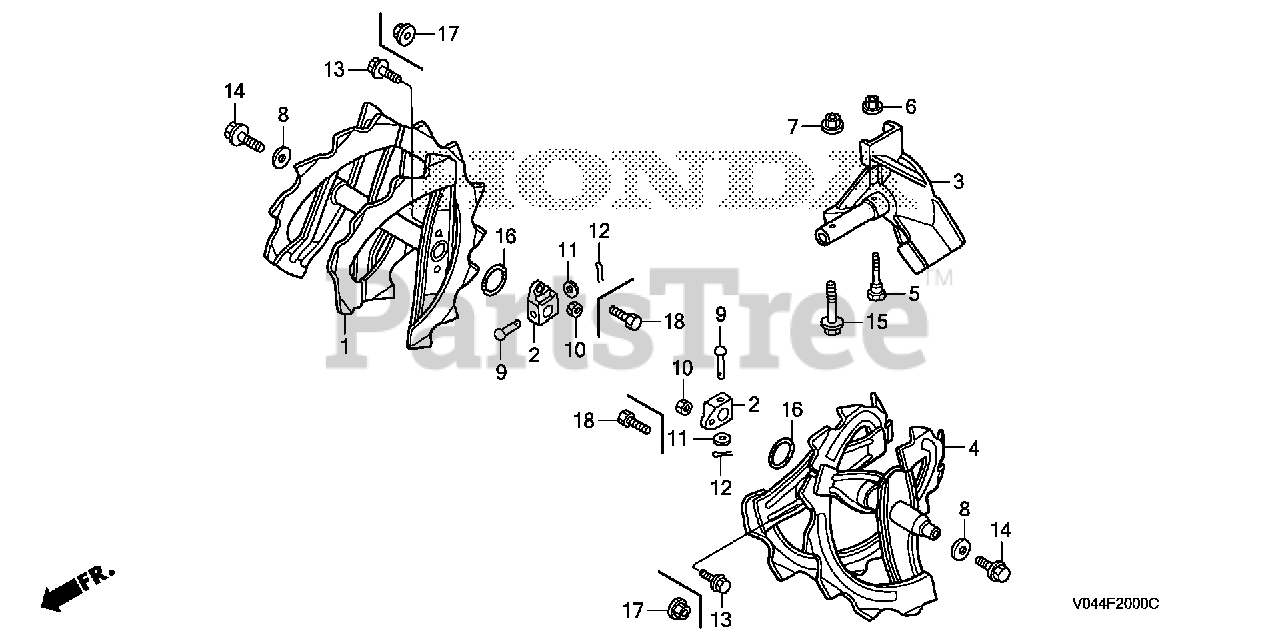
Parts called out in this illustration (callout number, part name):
2	BOSS, LOCK BOLT
5	BOLT, LOCK
6	NUT, SELF-LOCK (6MM)
7	NUT, FLANGE (8MM)
8	WASHER (8MM)
9	PIN (7X40)
11	WASHER, PLAIN (7MM)
12	PIN, SPLIT (3.0X25)
12	PIN, COTTER (3.0X45)
14	BOLT, FLANGE (8X16) Use from Engine SN 1000016.
15	BOLT, FLANGE (8X35)
16	O-RING (19.8X1.9) (ARAI)
17	NUT, SELF-LOCK (6MM)
18	BOLT, HEX. (6X16)
